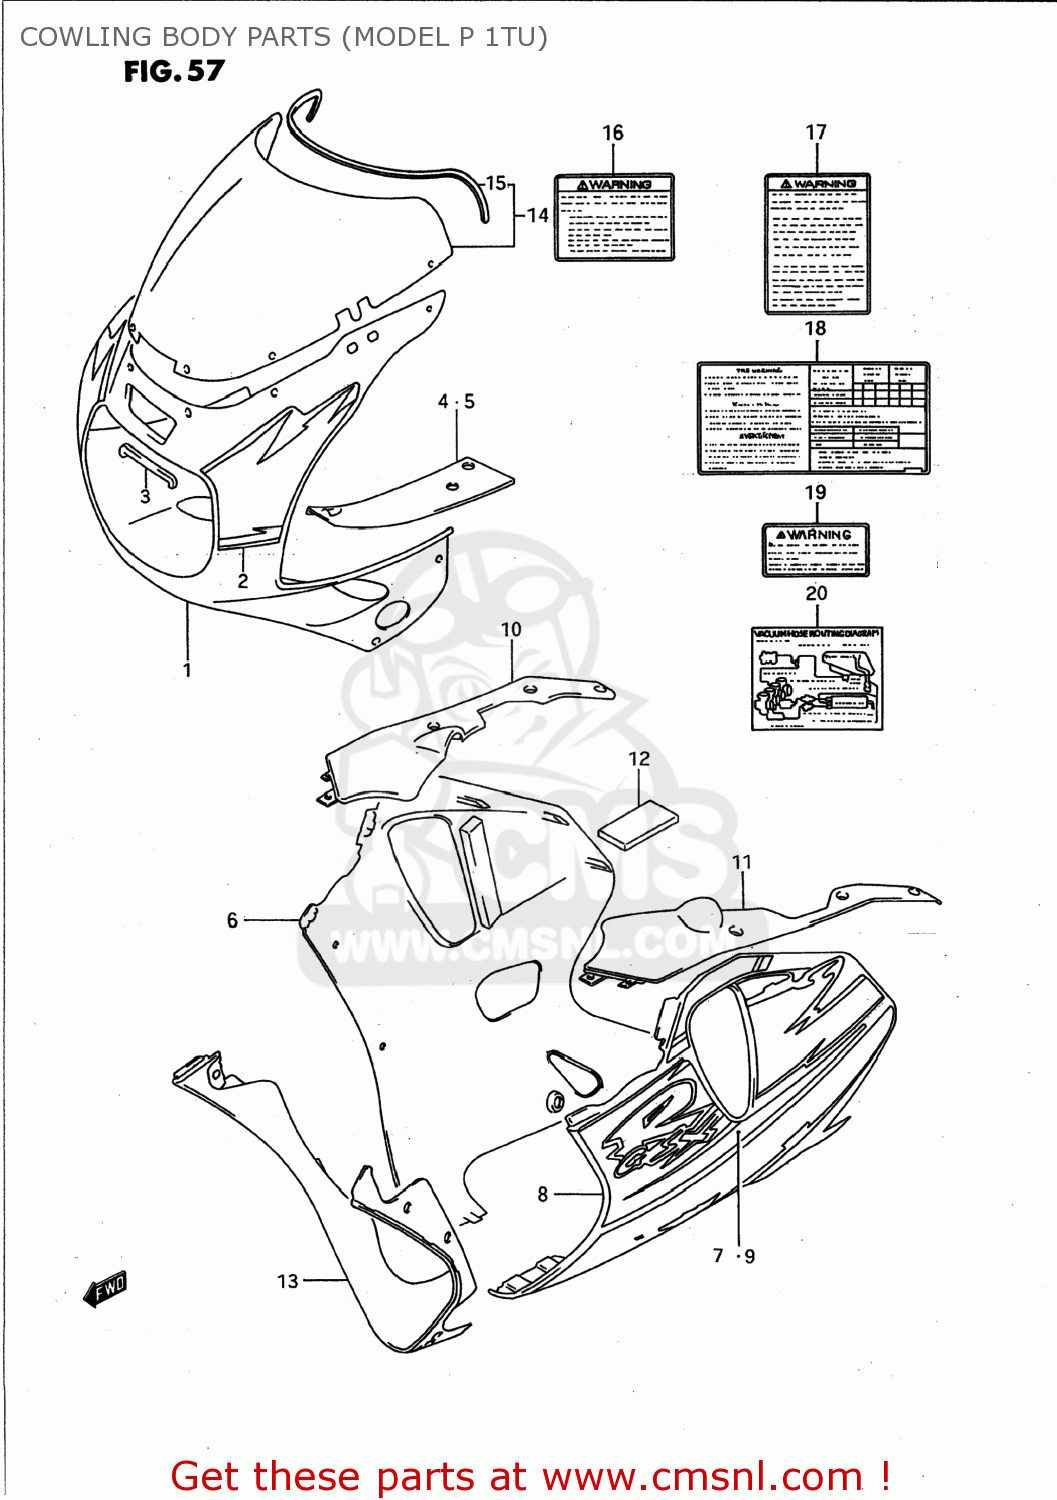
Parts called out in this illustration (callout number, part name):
1	COWLING ASSEMBLY,BODY
2	TAPE SET,COWLING BODY,FRONT
3	CUSHION,FR POSITION LAMP
4	PANEL,UPR,R
5	PANEL,UPR,L
6	COWLING ASSY,UNDER,R
7	TAPE SET,COWL UNDER,R
8	COWLING ASSY,UNDER,L
9	TAPE SET,COWLING,UNDER
10	PANEL,LWR,R
11	PANEL,LWR,L
12	CUSHION,PANEL
13	COWLING,UNDER CTR
14	WINDSCREEN SET
15	MOLDING
16	LABEL
17	LABEL (WARNING SCREEN)
18	LABEL (TIRE AIR PRESSURE)
19	LABEL,WARNING STEERING
20	LABEL (VACUUM HOSE ROUTING)
